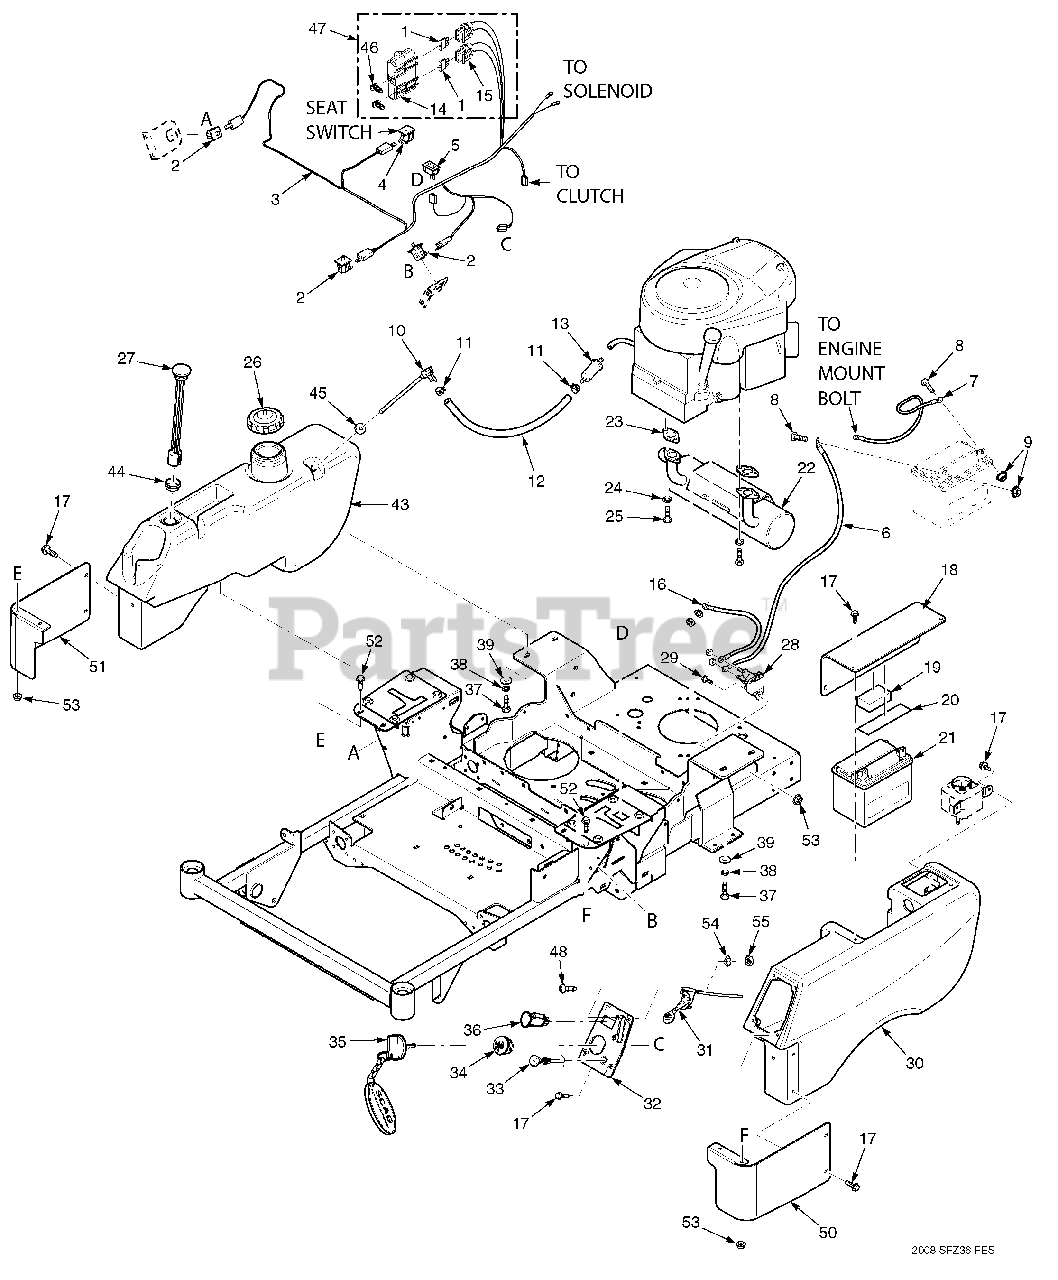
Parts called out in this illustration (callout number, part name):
1	Fuse, 20 amp
2	Switch
3	Wire Harness, Main
4	Switch, Seat
5	Hourmeter
6	Battery Cable, Red 25"
7	Battery Cable, Black 27"
8	Bolt, Hex Head 1/4-20 x 1/2"
9	Nut, 1/4-20
10	Fuel Tube Assembly
11	Clamp, Fuel Hose 1/4" ID
12	Fuel Hose, 1/4" ID Non-Perm
13	Fuel Filter
14	Cover, Sealed Double
15	Fuse Holder
16	Battery Cable, Red 9"
17	Bolt, Hex Head 1/4-20 x 1/2" Serr. Flange
18	Battery Cover
19	Pad, Battery Hold Down
20	Rubber Pad
21	Battery
22	Muffler, Briggs & Stratton
23	Exhaust Gasket
24	Lockwasher
25	Bolt
26	Cap, Fuel Tank
27	Fuel Gauge Assembly
28	Solenoid
29	Bolt, Hex Head 1/4-20 x 0.63"
30	Tank, LH
31	Throttle Cable, Briggs & Stratton
32	Instrument Panel w/Decal
33	Choke Cable, Briggs & Stratton
34	Ignition Switch
35	Key, Ignition
36	PTO Switch
37	Bolt, Hex Head 5/16-18 x 3/4"
38	Lockwasher, 5/16" Spring
39	Flatwasher, 5/16-.375 x .875 x .083
40	Bolt, Hex Head 5/16-18 x 1-1/2"
41	Bolt, Hex Head 3/8-16 x 1-1/4" Special Lock
42	U-Nut, 3/8-16
43	Fuel Tank Assembly, RH
44	Grommet
45	Bushing, 0.56" Dia. Viton
46	Clip, Wire
47	Double Fuse Assy.
48	Screw, #10-32 X 3/4"
49	Nut, Serrated Flange #10-32
50	Control Cover, LH
51	Control Cover, RH
52	Bolt, Hex Head 1/4-20 x 3/4" Serr. Flange
53	Nut, Serrated Flange 1/4-20
54	Lockwasher, #10 External Tooth
55	Nut, Hex #10-32
